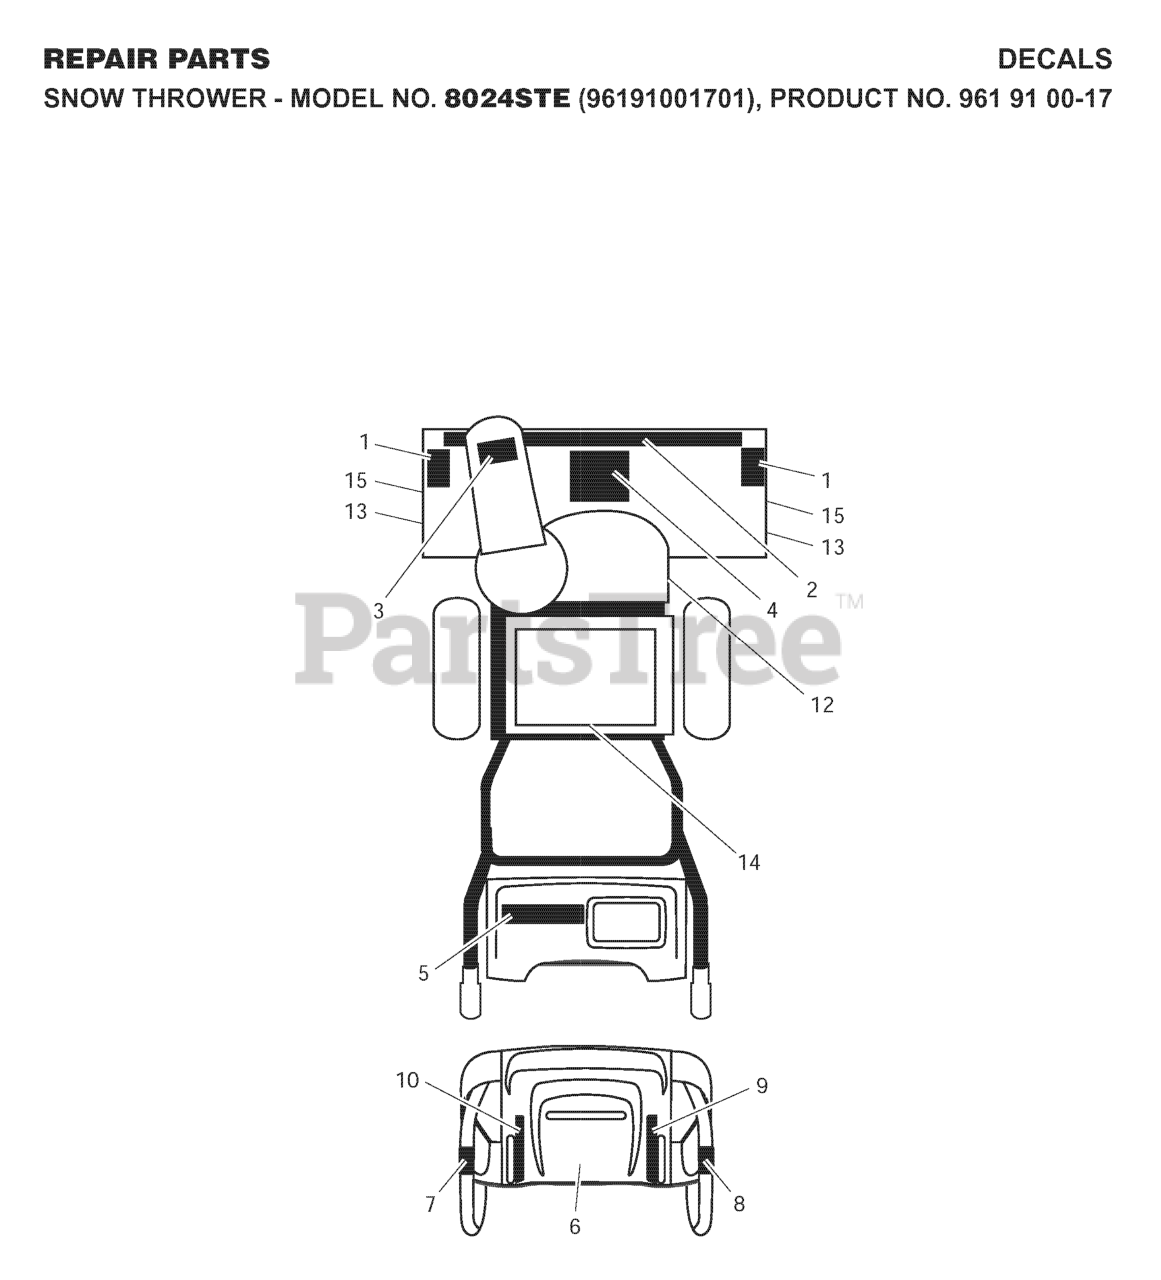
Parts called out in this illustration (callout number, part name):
1	DECAL.AUGER.SAFETY.
3	DECAL.CHUTE.SAFETY.
4	DECAL.AUGER."
6	DECAL.CONSOLE.INSTRUCTION
10	DECAL.REM.DEFLECTOR.LT
12	DECAL.BELT.GUARD.
14	DECAL.FENDER
15	DECAL, HUSQVARNA
